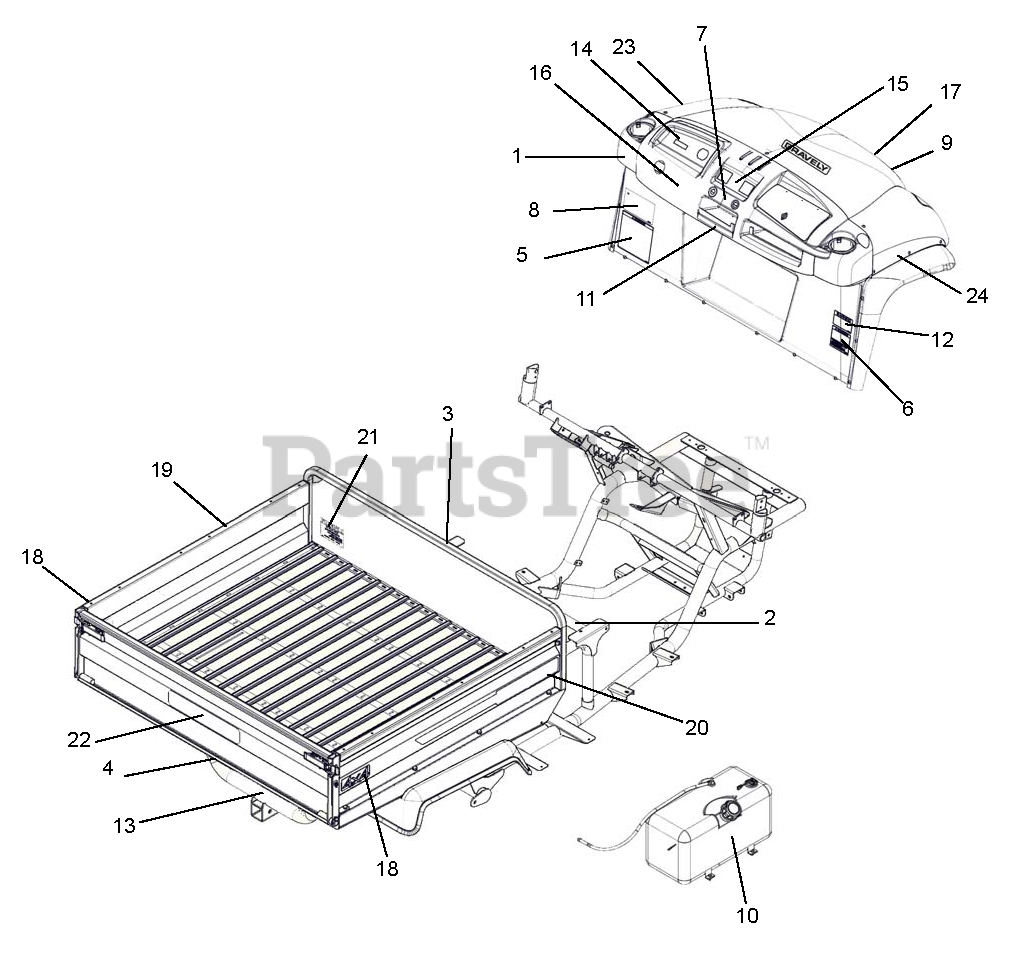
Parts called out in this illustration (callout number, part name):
1	DECAL, ARIENS HERITAGE - SMALL
2	DECAL DANGER PD GUARD MISS SML
3	DECAL DANGER BATTERY
4	DECAL DANGER HOT
5	DECAL WARNING GNRAL UTLTY VHCL
6	DECAL WARNING ROLLOVER HAZARD
7	DECAL, HAND BRAKE
8	DECAL WARNING IMPROPER USE
9	DECAL CAUTION PWR SRC MAX 12V
10	DECAL WARNING ENG. COOL B4 GAS
11	DECAL WARNING VEHICLE ROLLOVER
12	4X2 GVW - PAYLOAD INFORMATION
12	4X4 GVW - PAYLOAD INFORMATION
13	LABEL TRAILER TOWING 1500 LB
14	DECAL, START INSTRUCTION
15	DECAL, SWITCH PANEL 4X4
15	DECAL, SWITCH PANEL 4X2
16	DECAL, SHIFT INSTRUCTION
17	TAG, BATTERY DISCONNECT
18	DECAL,ORANGE,4X4
18	DECAL,ARIENS,4X2, ORANGE
19	DECAL,ARIENS,BEDSIDE,LH SIDE
20	DECAL,ARIENS,BEDSIDE,RH SIDE
21	DECAL WARNING PINCH PT/CRUSH
22	DECAL, ARIENS JEWEL
23	DECAL, HOOD LH, CONTRACTOR
24	DECAL, HOOD RH, CONTRACTOR
